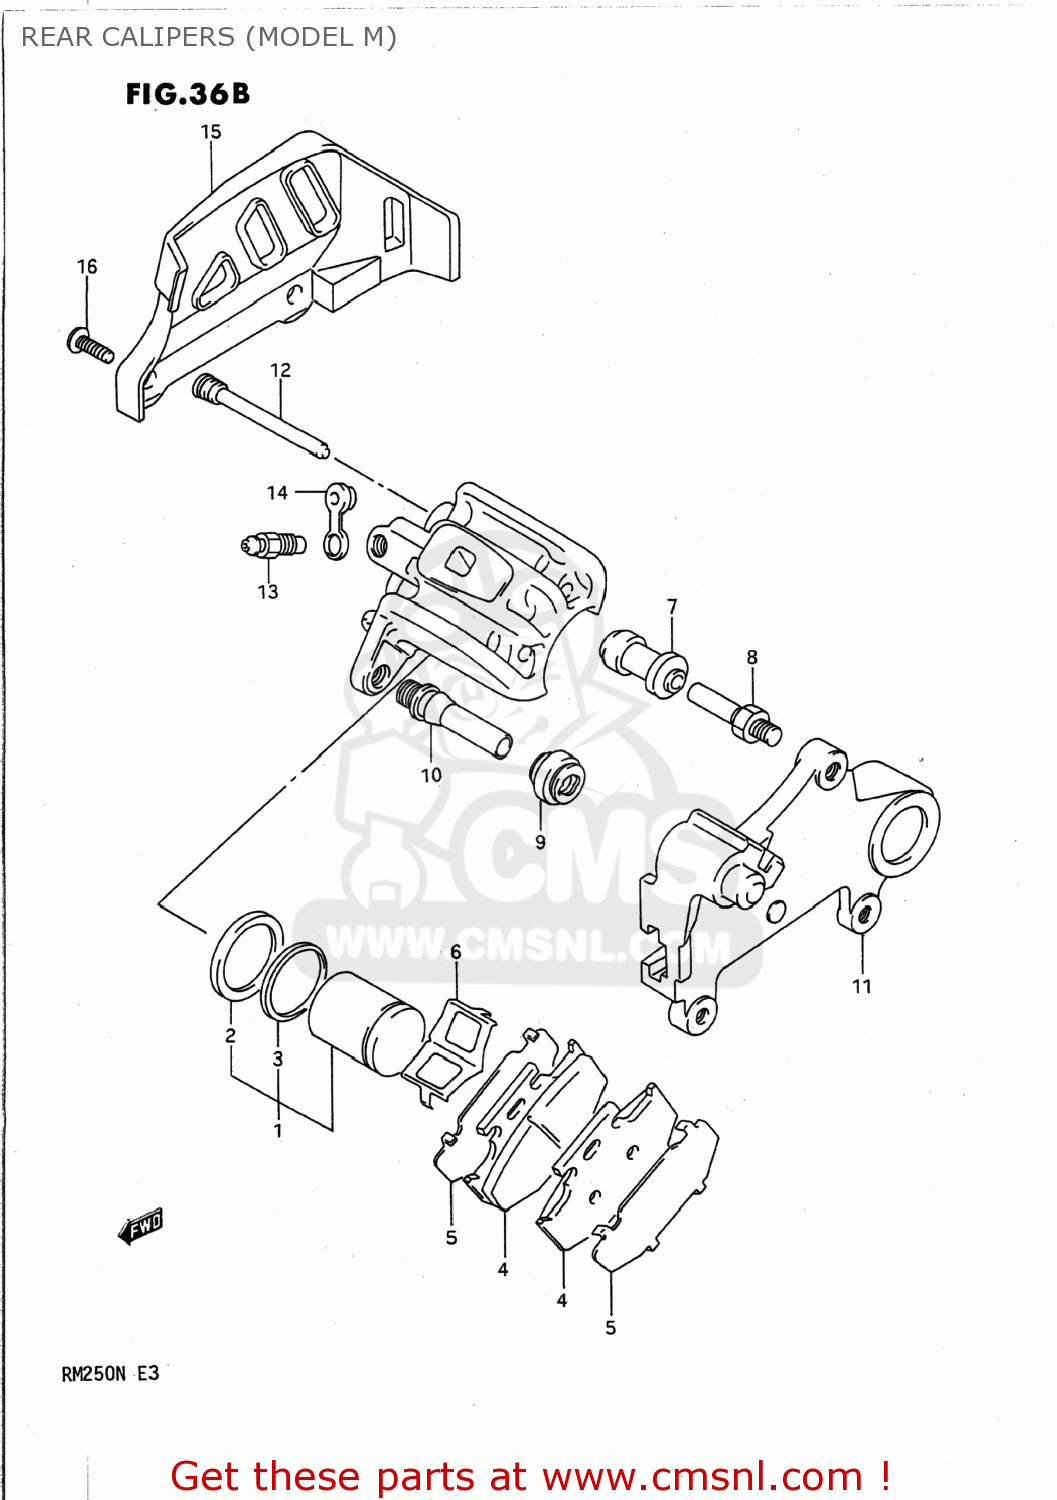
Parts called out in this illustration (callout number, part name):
1	PISTON SET
2	SEAL,PISTON
3	SEAL,DUST
4	PAD
5	SHIM
6	SPRING,PAD
7	BOOT
8	PIN,BOLT
9	BOOT
10	PIN
11	BRACKET
12	PIN,HANGER
13	BLEEDER
14	CAP,BLEEDER
15	GUARD,RR CALIPER
16	SCREW(6X12)
